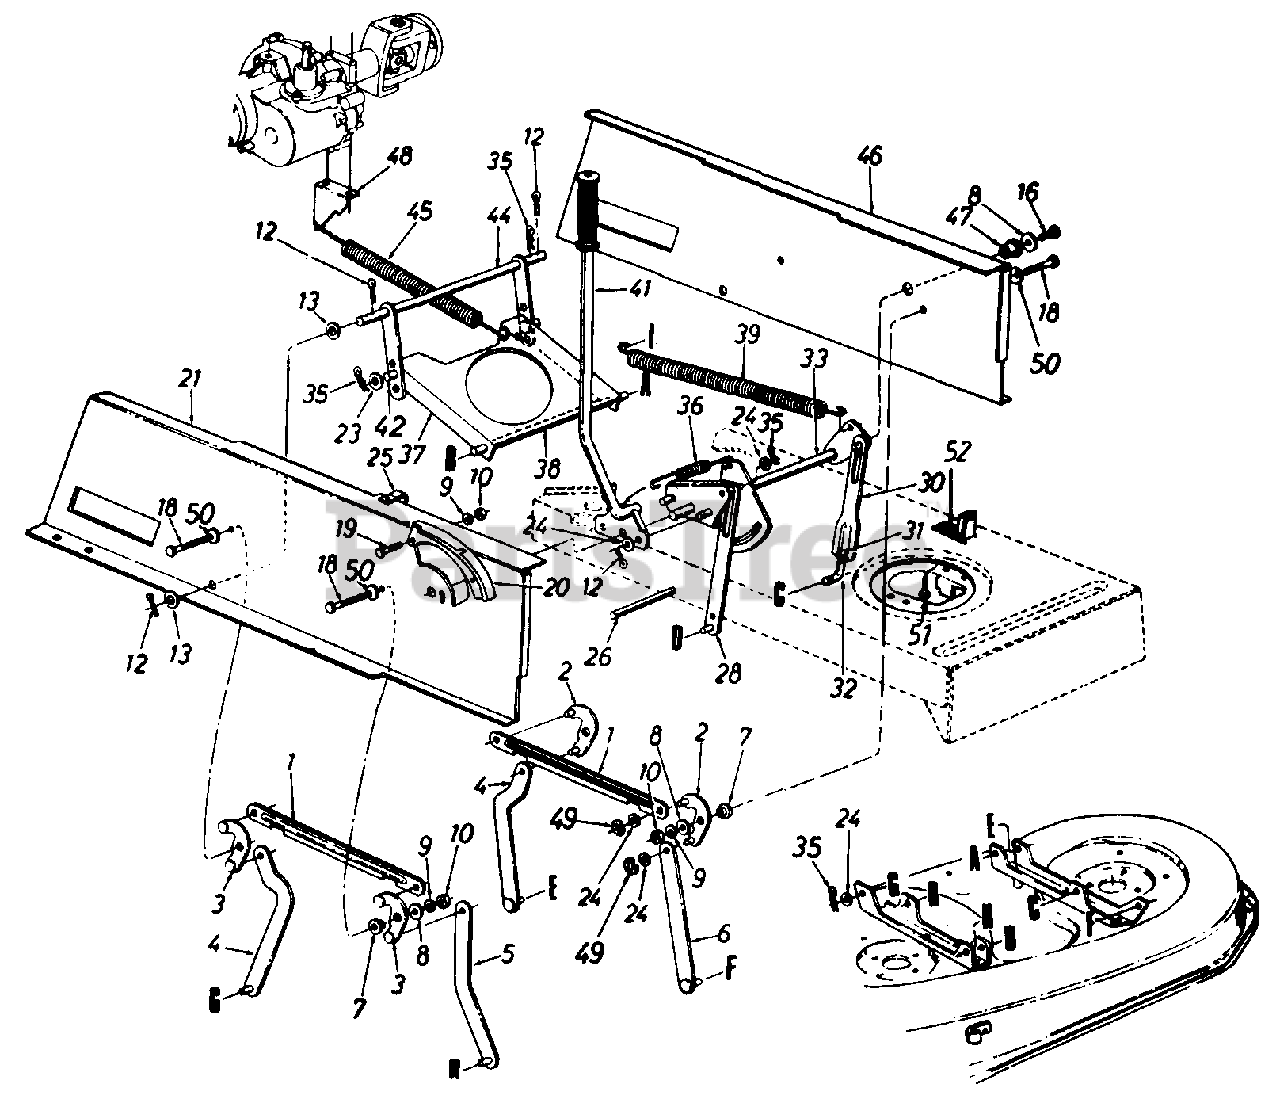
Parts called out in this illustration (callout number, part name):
3	Pivot Link Ass'y.- R.H.
7	Shld. Spacer .318" I.D.
8	Fl-Wash. .344" I.D. x .62" O.D.
9	L-Wash. 5/16" I.D.
10	Sems Nut 1/4-20 Thd.
12	Cotter Pin 1/8" Dia.
13	Fl-Wash. .635" I.D. x 1.0" O.D.
16	Hex Wash. Tl-Tap Scr. 5/16-18 x .75" Lg.
18	Hex Wash. Hd. Scr. 5/16-18 x .875" Lg.
19	Hex Bolt 5/16-18 x .75" Lg.
21	Upper Frame - R.H.
23	Fl-Wash. .385" I.D. x .87" O.D.
24	Fl-Wash. .531" I.D. x .93" O.D.
26	Running Board Rod
31	Hex Nut 1/2-20 Thd. (Gr. 5)
32	Lift Link Adjuster
33	Lift Shaft Ass'y.
35	Inter. Cotter Pin 3/8" Dia.
36	Extension Spring
39	Extension Spring
46	Upper Frame - L.H.
47	Flange Brg. .632" I.D.
49	"E"-Ring
50	Bell-Wash. .325" I.D.
51	Hex Wash. Hd. TT-Tap Scr. 1/4-20 x .5" Lg.
52	Spring Switch
97675A-0637	LIFT HANDLE ASSY POWDER BLACK - POWDER BLACK (0637)
97675A-0638	LIFT HANDLE ASSY POWDER BLACK - MTD/TROY-BILT RED (0638)
97675A-0648	LIFT HANDLE ASSY POWDER BLACK - TECH GRAY (0648)
97675A-0665	LIFT HANDLE ASSY POWDER BLACK - YARDMAN GREEN (0665)
